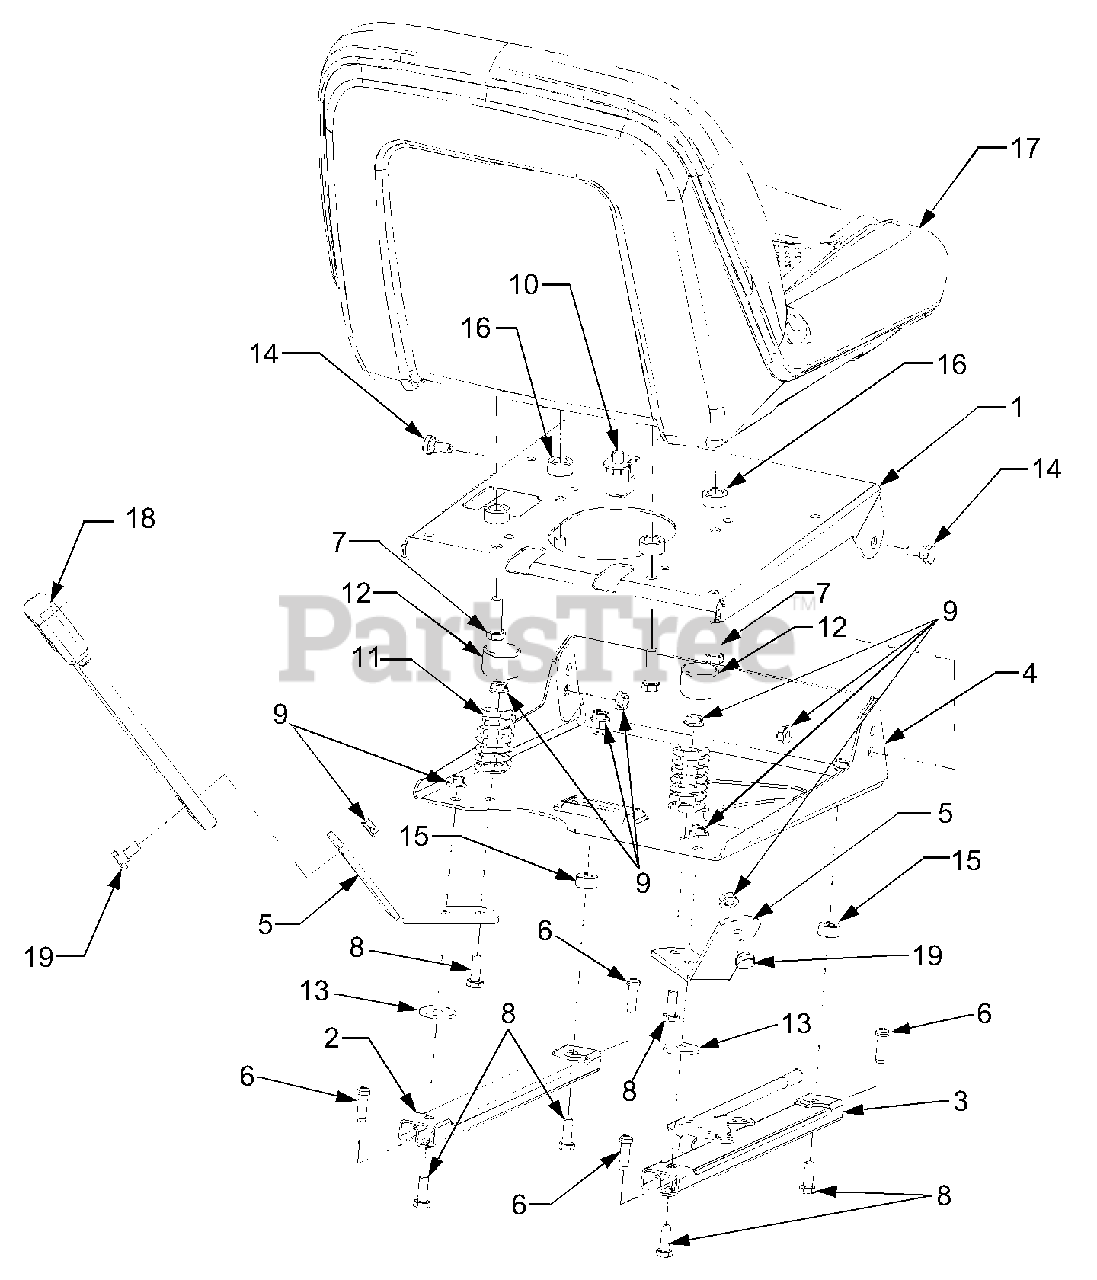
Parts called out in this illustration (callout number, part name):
1	Bracket, Seat Pivot
2	Track, Seat - w/o Latch
3	Track, Seat - w/Latch
4	Bracket, Seat Support
5	Bracket, Seat Belt
6	Screw, Pan Hd. Mach. 5/16-18 x 1.0
7	Screw, Hex Cap, 3/8-16 x 1.25 GR5
8	Screw, Hex Cap, 5/16-18 x 1.0 GR5
9	Nut, Hex Insert Flange Lock 5/16-18 GR5
10	Switch, Seat, N/O
11	Spring, Compression
12	Cap, Spring
13	Washer, Flat, .33 x 1.25 x .12 .
14	Screw, Shoulder, .435 x .178:5/16-18
15	Spacer, .315 x .75 x .375
16	Spacer, .505 x .88 x .44
17	Seat, High Back
18	Belt Assembly, Seat
19	Tie, Push Mnt. Cable
